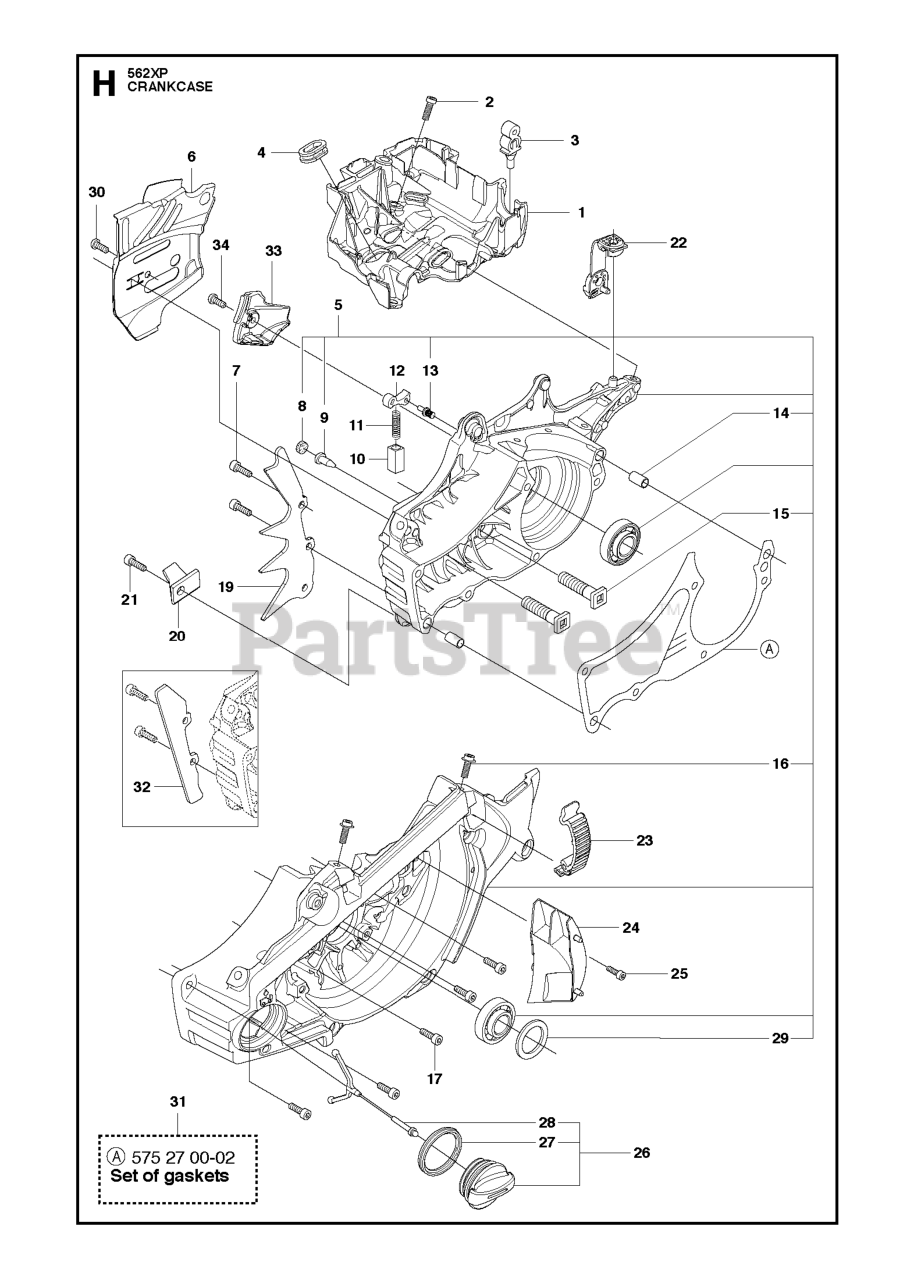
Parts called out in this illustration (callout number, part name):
1	CARBURETTOR AREA BASE
3	SUPPORT
5	CRANKCASE
6	CHAIN GUIDE PLATE
8	PLUG
9	VALVE-CHECK (DUCKBILL)
11	LOCK SPRING
13	PIN
14	SLEEVE
15	BAR BOLT
16	SCREW IHSCM
17	SCREW IHSCM
20	CHAIN CATCHER
22	DEFLECTION LIMITER
23	CLIP GRAY
24	AIR NOZZLE
25	SCREW IHSCM
26	TANK CAP ASSY
27	SEALING
28	HOLDER
29	RADIAL SEAL
30	SCREW CITXPANT
31	GASKET KIT
32	RP ENCLOSED KIT
33	CHAIN GUIDE
